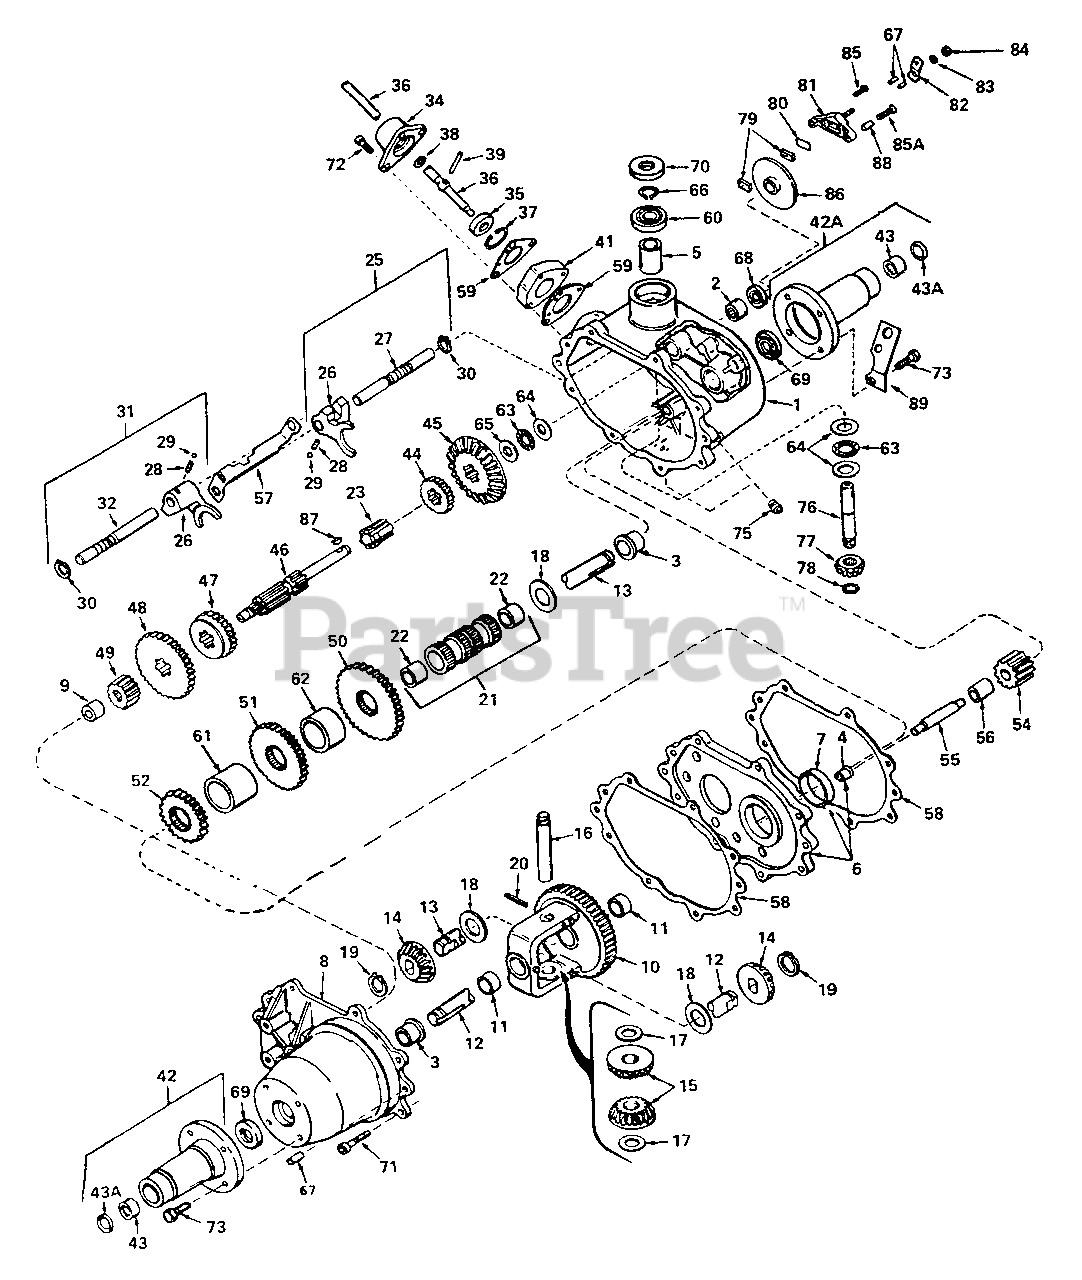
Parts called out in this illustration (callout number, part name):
1	CASE ASSY, Transaxle (Incl. Nos. 2, 3 & 5)
2	BEARING, Needle
3	BEARING, Bronze
4	BEARING, Bronze
5	BEARING, Bronze
6	PLATE ASSY, Center (Incl. Nos. 4 & 7)
7	BEARING, Bronze
8	COVER ASSY, Transaxle (Incl. Nos. 3 & 9)
9	BEARING, Needle
10	GEAR ASSY, Differential (Incl. No. 11)
11	BEARING, Bronze
12	AXLE, Left Hand
13	AXLE, Right Hand
14	GEAR, Bevel
15	PINION, Bevel
16	PIN, Drive
17	WASHER, Thrust
18	WASHER, Thrust
19	RING, Snap
20	PIN, Roll
21	SLEEVE ASSY, Countershaft (Incl. No. 22)
22	BEARING, Bronze
23	SHAFT, Idler
25	ROD ASSY, Shift (1st & 2nd)(Incl. Nos. 26 thru 30)
26	FORK, Shift
27	ROD, Shift
29	BALL, Steel
30	RING, Snap
31	ROD ASSY, Shift (2nd & 3rd)(Incl. Nos. 26,28,29,30 & 32)
32	ROD, Shift
34	HOUSING, Shift Lever
35	KEEPER, Shift Lever
36	LEVER, Shift
37	RING, Snap
38	RING, Quad
39	PIN, Drive
41	BLOCK, Riser
42	HOUSING ASSY, Axle (Incl. No. 43)
42A	HOUSING ASSY, Axle (Incl. No. 43)
43	BEARING, Needle
43A	SEAL, Oil
44	GEAR (16 Teeth)
45	GEAR, Bevel (33 Teeth)
46	SHAFT, Shifter & Brake
47	GEAR, Shifting (2nd & 3rd)
48	GEAR, Shifting (1st & Rev.)
49	GEAR, Spur (12 Teeth)
50	GEAR, Countershaft Drive (39 Teeth)
51	GEAR, Countershaft (34 Teeth)
52	GEAR, Countershaft (25 Teeth)
54	IDLER, Reverse
55	SHAFT, Reverse Idler
56	SPACER, Reverse Idler
57	STOP, Shifter
58	GASKET, Case & Cover
59	GASKET, Shift Lever Housing
60	BEARING, Ball
63	BEARING, Thrust
64	WASHER, Thrust
65	WASHER, Thrust
66	RING, Snap
67	PIN, Dowel
68	SEAL, Oil
69	SEAL, Oil
70	SEAL, Oil
71	CAPSCREW, Socket Hd., 1/4-20 x 1-1/4
72	CAPSCREW, Socket Hd., 1/4-20 x 1-3/4
73	SCREW, Hex Hd., Sems, 5/16-18 x 1
75	PLUG, Pipe, 1/8"
76	SHAFT, Input
77	PINION, Input
78	RING, Retaining
79	PAD, Brake
80	PLATE, Brake Pad
81	HOLDER, Brake Pad
82	LEVER, Brake
83	WASHER, Flat
84	NUT, Lock
85	CAPSCREW, Hex Hd., Thd. Forming, 1/4-20 x 1-1/4
85A	SCREW, Hex Hd., Thd. Forming, 1/4-20 x 2-1/4
86	DISK, Brake
87	KEY, Woodruff #61
89	BRACKET, Spring Anchor
